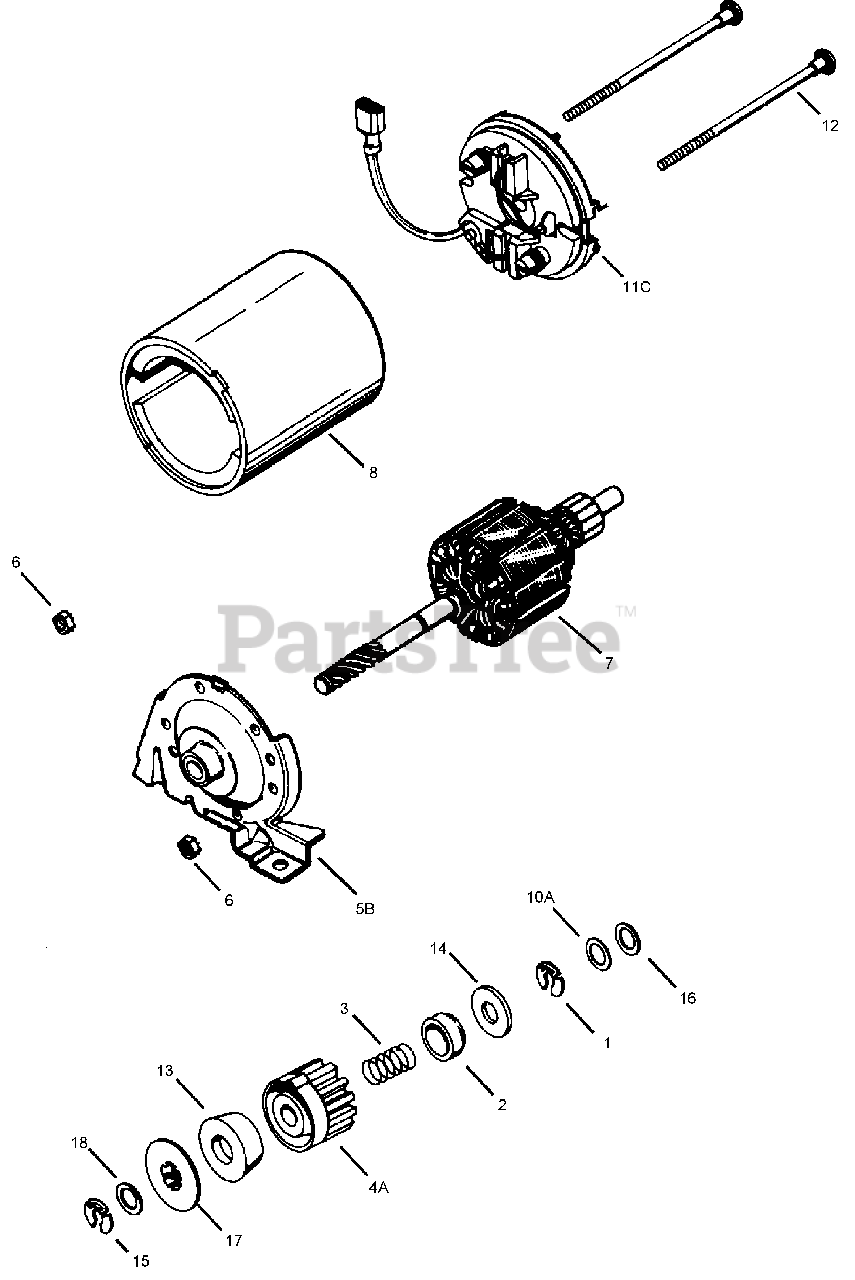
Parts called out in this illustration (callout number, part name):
1	Ring-Retaining
2	Retainer-Spring
3	Spring
4A	Gear
5B	Drive End Cap ASM
6	Nut-Lock
7	Armature
8	Housing ASM
10A	Washer-Thrust
11C	Commutator End Cap ASM (Includes Brushes)
12	Bolt
13	Driver-Pinion
14	Washer-Cup
15	Ring-Retaining
16	Washer
17	Nut-Drive
18	Washer
